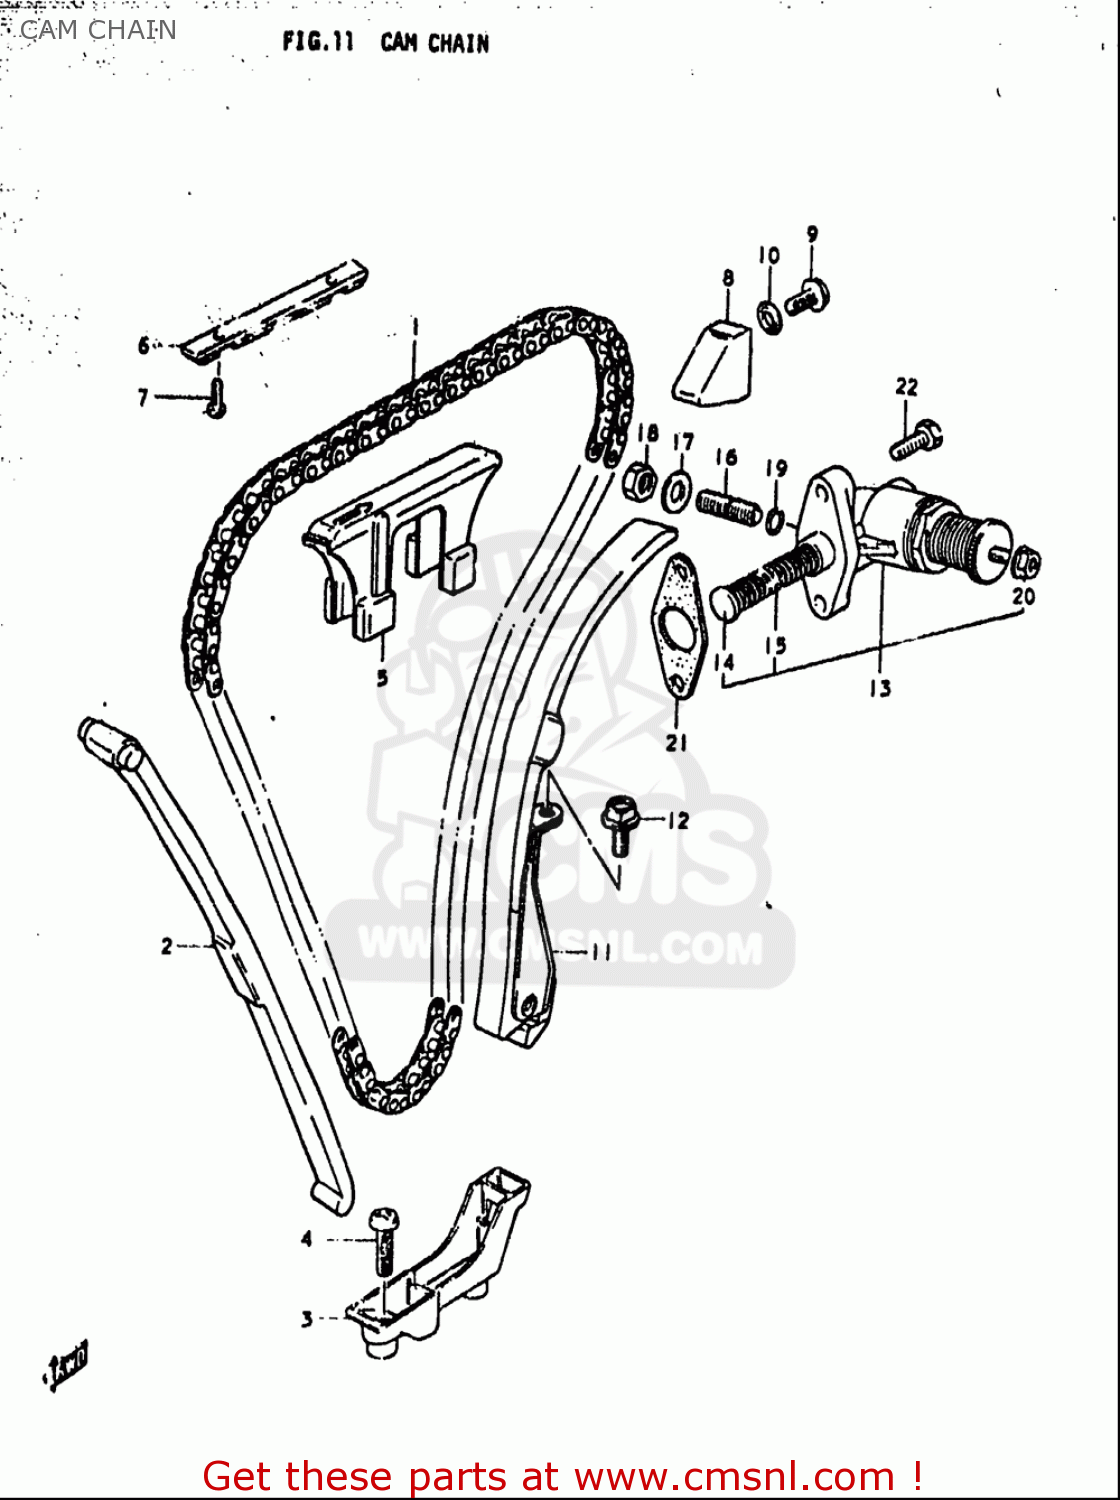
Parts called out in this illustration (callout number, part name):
1	CHAIN,CAMSHAFT DRIVE(120L)
2	GUIDE,CAM CHAIN NO.1
3	HOLDER,CAM CHAIN GUIDE
4	SCREW
5	GUIDE,CAM CHAIN NO.2
6	GUIDE,CAM CHAIN NO.3
7	SCREW
8	GUIDE,CAM CHAIN
9	BOLT
10	GASKET(5.8X13X1.2) (NAS)
11	TENSIONER,CAM CHAIN
12	BOLT
13	ADJUSTER,CAM CHAIN TENSIONER
14	ROD,PUSH
15	SPRING
16	SCREW
17	WASHER
18	NUT
19	O RING(D:1.9,ID:5.7)
20	NUT
21	GASKET,TENSIONER ADJUSTER (NAS)
22	SCREW (6X25)
